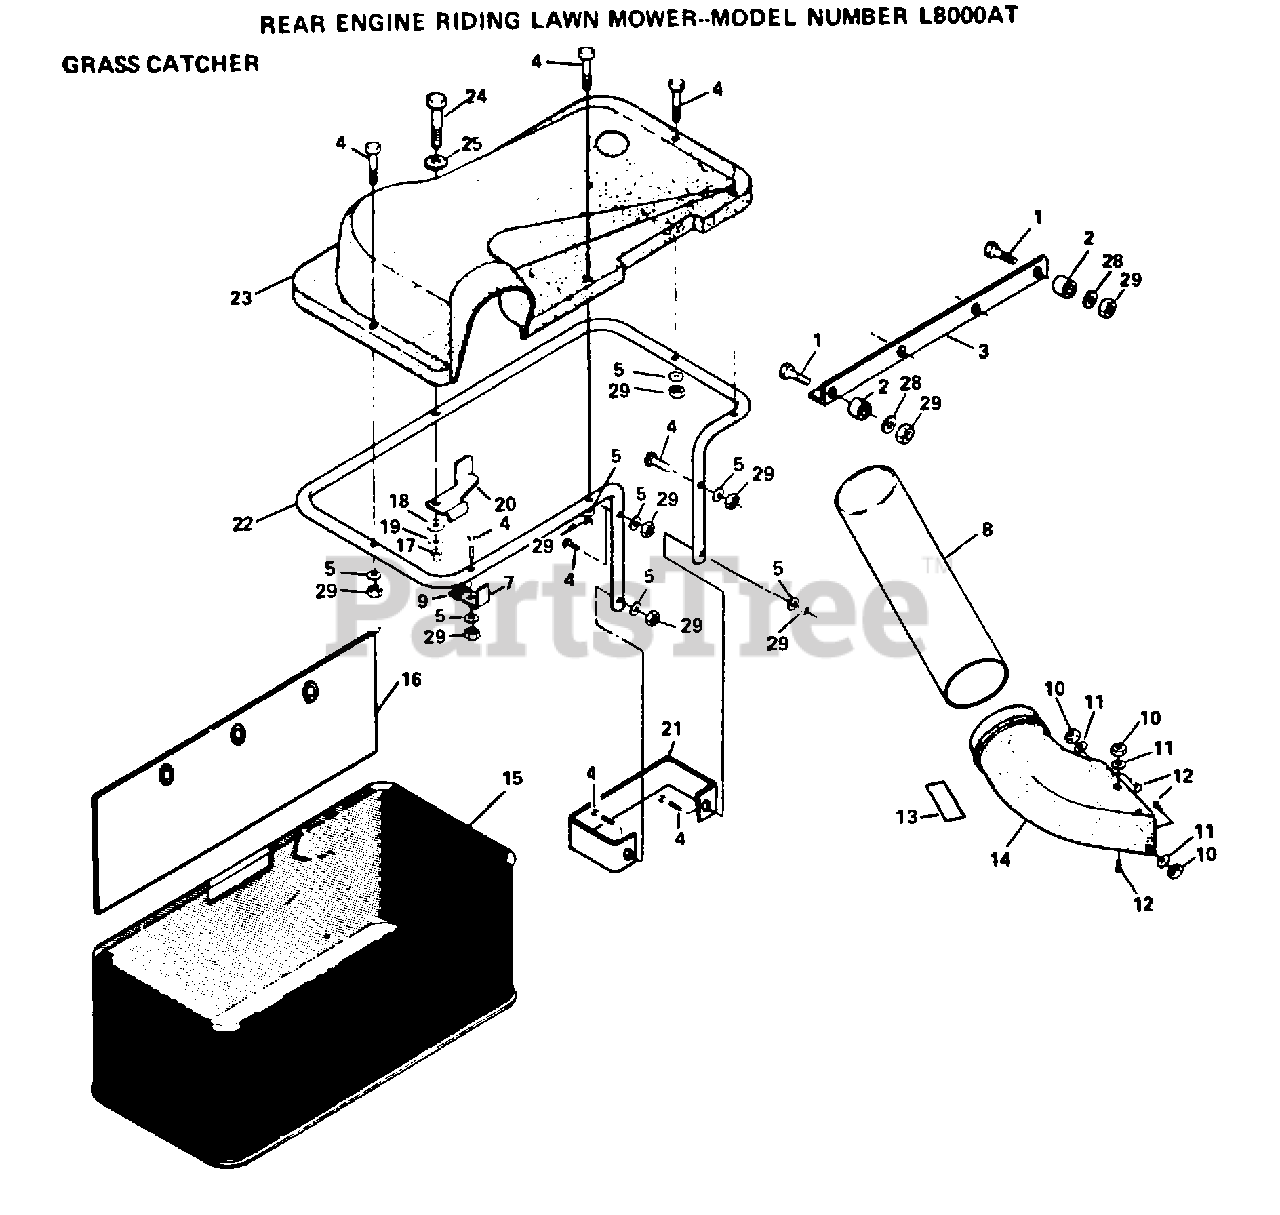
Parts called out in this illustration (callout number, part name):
1	CAPBEAR ASSY
2	TRANSFER GEAR CASE ASSY
3	NUT.HEX.5/16-18
5	GEAR SHAFT L RE
6	BOLT
9	SPACKER - SPROCKET
